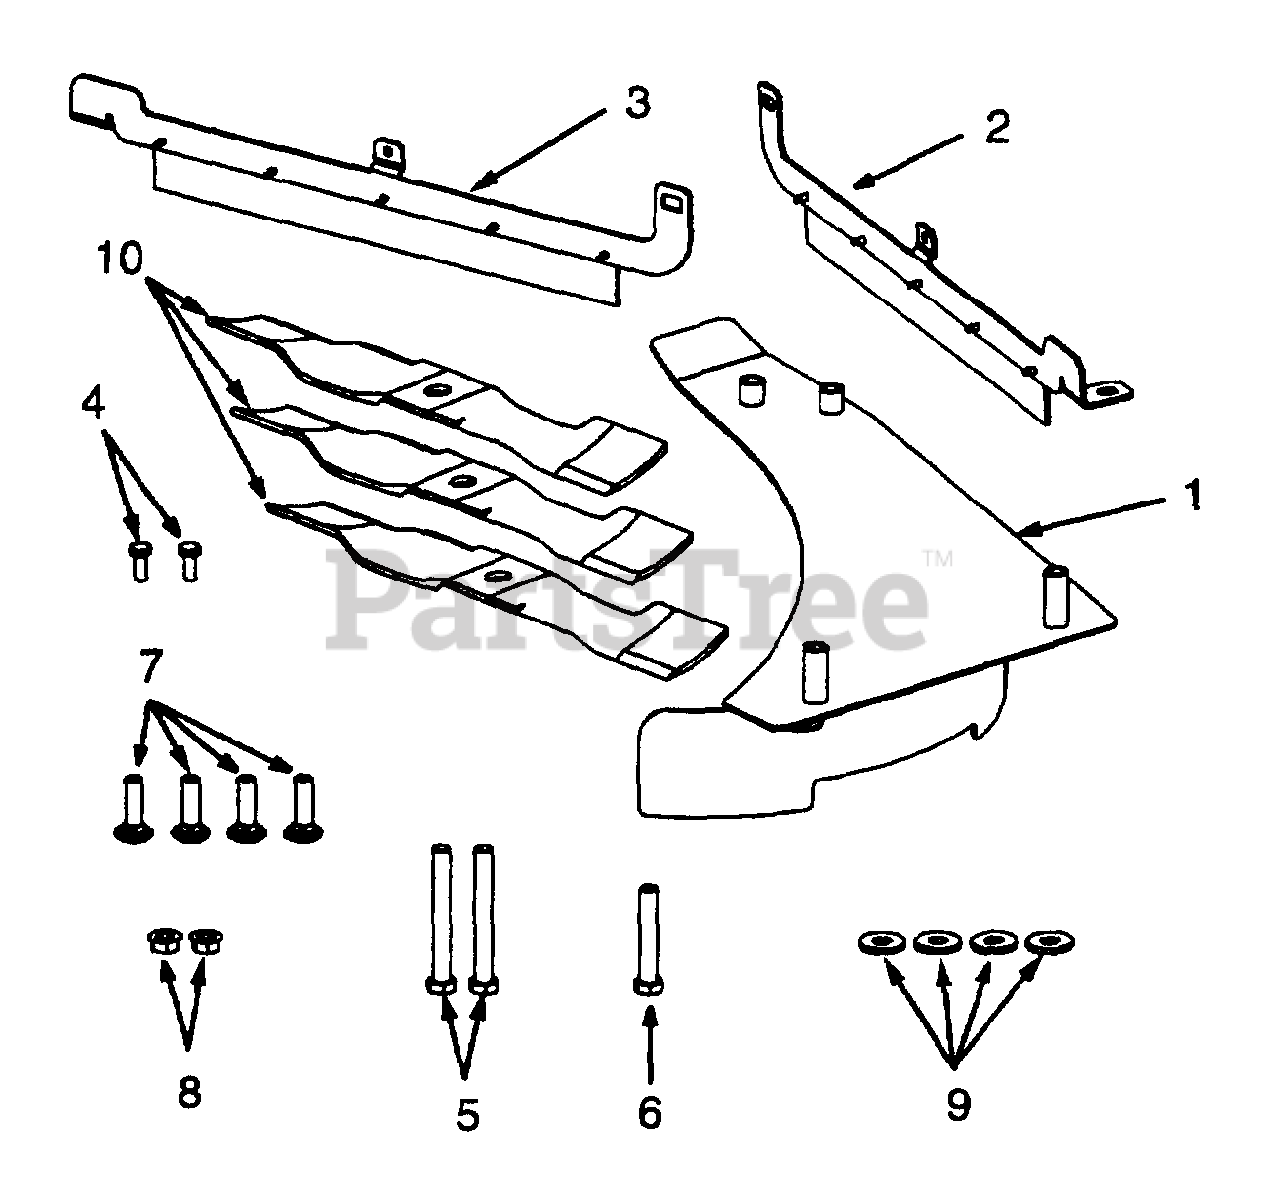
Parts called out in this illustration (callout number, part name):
1	Baffle Ass'y, 54" Mulching
2	Bracket Ass'y, Rubber Flap/Mtg RH
3	Bracket Ass'y, Rubber Flap/Mtg LH
4	Screw, Hex Cap, 1/4-20 x .62 GR5
5	Screw, Hex Cap, 3/8-16 x 2.75 GR5
6	Screw, Hex Cap, 3/8-16 x 1.75
7	Bolt, Carriage, 3/8-16 x 1.0 GR5
8	Nut, Hex Flange Lock,1/4-20
9	Washer, Flat, .406 X 1.0 X .105
10	Blade, Mulching, 18.5 Lg
